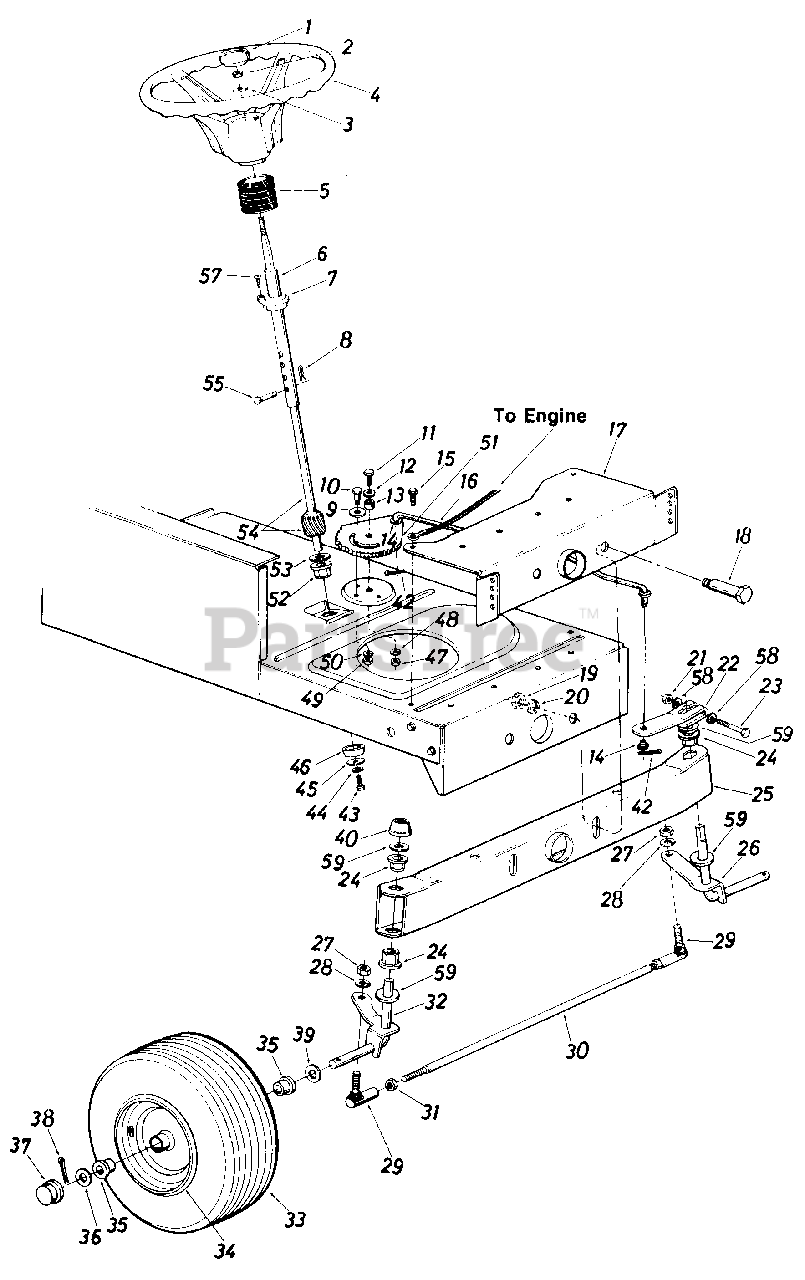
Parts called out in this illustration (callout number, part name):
1	Steering Wheel Cap
2	Hex Nut 5/16-18 Thd.*
3	Belleville Wash. .345" I.D.
4	Steering Wheel
5	Steering Bellow 4.5"
6	Steering Column Ass'y.
7	Flange Bearing .890 I.D. x 1.36 O.D.
8	Internal Cotter Pin 1/4" Dia.
9	Fl-Wash. .438" I.D. x 1.37" O.D.
10	Shoulder Bolt .437" Dia. x .35 Lg. 5/16-18 Thd.
11	Hex Bolt 3/8-24 x 1.0" Lg. (Grade 5)
12	Fl-Wash. .38" I.D. x 1.0" O.D.
13	Spacer .380" I.D. x .625" O.D. x .227
14	Flat Washer .56 I.D. x 1.0 O.D.
15	Hex Wash. Hd. Self-Tap Scr.
16	Steering Drag Link
17	Front Pivot Brkt.
18	Shoulder Bolt .498" Dia. x 2.04 Lg. 3/8-16 Thd.
19	Hex Nut 3/8-16 Thd.*
20	L-Wash. 3/8" I.D.*
21	Hex Cent. L-Nut 5/16-24 Thd.
22	Steering Arm Front Axle
23	Hex Bolt 5/16-24 x 2.00" Lg. (Grade 5)
24	Hex Flg. Brg. .634 I.D.
26	Front Axle Ass'y. L. H .
27	Hex Nut 3/8-24 Thd.*
28	L-Wash. 3/8" I.D.*
29	Ball Joint 3/8-24 Thd.
31	Hex Jam Nut 3/8-24 Thd.*
32	Front Axle Ass'y. R.H.
33	Wheel Ass'y. Comp.
34	Front Wheel Rim Only
35	Bearing
36	Fl-Wash. .635 I.D. x 1.59" O.D.
37	Front Wheel Hub Cap
38	Cotter Pin 118" Dia. x 1.25" Lg.*
39	Fl-Wash. .635" I.D. x 1.20" O.D.
40	Push Cap 5/8" Dia. Rod
42	Cotter Pin 118" Dia. x 1.0" Lg.
43	Hex L-Bolt 5/16-18 x .62" Lg.*
44	L-Wash. 5/16" I.D.*
45	Fl-Wash. .344" I.D. x 1.25" O.D.
46	Spacer (Plastic)
47	Hex Nut 3/8-24 Thd.*
48	L-Wash. 3/8" I.D.*
49	Hex Nut 5/16-18 Thd.*
50	L-Wash. 5/16" I.D.*
51	Steering Gear Segment
52	Hex Flg. Brg. .634 I.D.
53	Fl-Wash. (Hardened)
54	Steering Shaft Lower
55	Clevis Pin 1/4" Dia. x 1.00" Lg.
57	Oval Hd. Cr. Sunk Scr. #10 x 5/8" Lg.
59	Fl-Wash. (Hardened)
